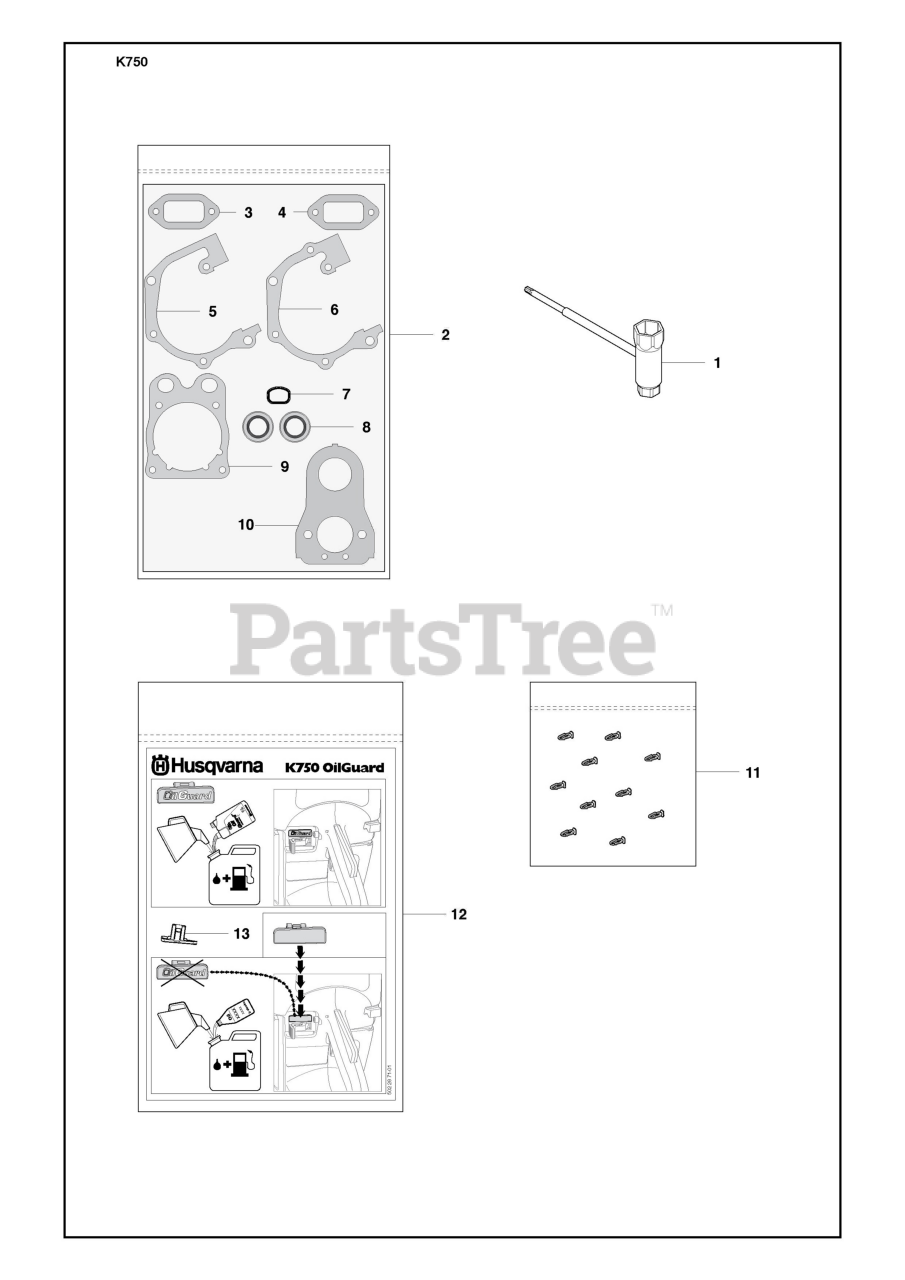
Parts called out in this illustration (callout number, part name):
1	Combination Tool
2	Gasket Kit
4	Gasket Muffler
5	Gasket Crankcase
6	Gasket Crankcase
8	Sealing Ring
9	Cylinder Base Gasket
10	Gasket Carburettor
11	Kit Break Pin
12	Kit Switch Off
